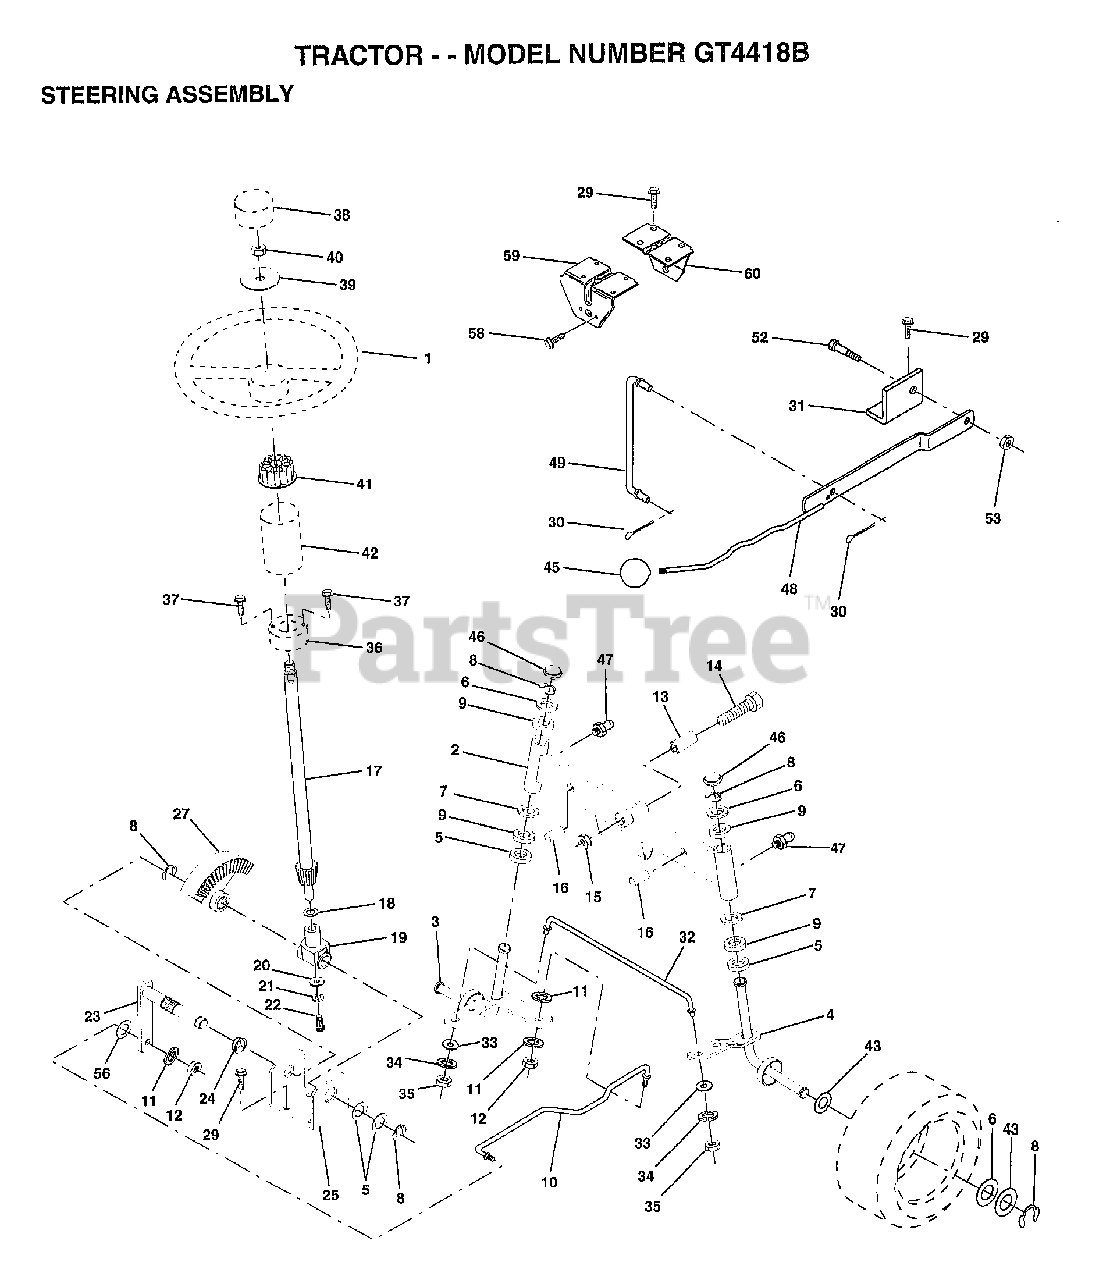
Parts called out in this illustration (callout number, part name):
2	AXLE ASM FRONT
4	MANUAL.O.YERT5E.F
5	WASHER .T
6	WASHER
7	WASHER
8	RING
9	COL. SRTG. BEAR.
11	LOCKWASHER
13	BEARING
14	BOLT LT
15	"NUT-LOC,FLANGE LT"
16	AXLE PIN
17	SHAFT&GEAR STR T
18	THRUST WASHER
19	SUPPORT.SHAFT
21	LOCKWASHER
22	"SCREW,SPECIAL"
24	NYLINER T
25	"BRKT,STEERING"
27	GEAR SECTOR
29	SCREW
30	COTTER PIN
31	BRKT.PVT.MAN.LVR.
32	ROD.TIE.19.75
33	WASHER M
34	LOCKWASHER
35	NUT.LOCK.5/16-24
38	ST WHL INSERT CAP
39	WASHER
41	ADAPTER LT
43	WASHER
45	KNOB T (1/2-HOLE)
46	CAP
47	ZERK M
48	LEVER ASSY T
49	LINK CLTCH W/NUTS
52	"BOLT, SHOULDER LT"
56	WASHER
58	SCREW LT
59	SUPPORT-SADDL T
60	SUPPORT.SADDLE.FT
